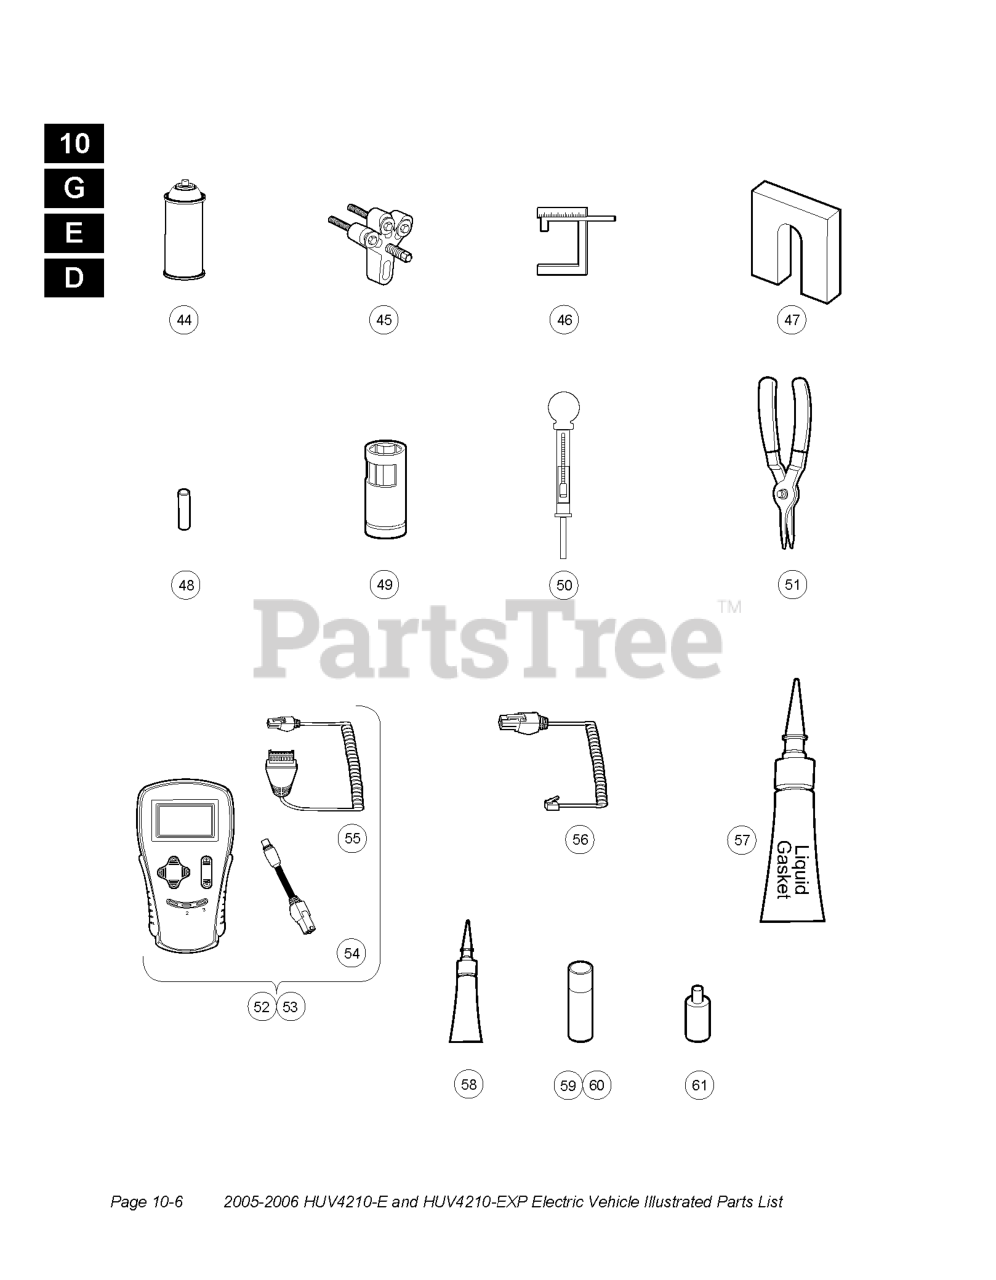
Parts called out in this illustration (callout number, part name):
44	LUBRICANT 11OZ CAN SPRAY
49	ADJUSTER, HYDRAULIC BRAKE
50	HYDROMETER
51	INERNAL RETAINING RING PLIERS
52	KIT, IQDM, USER, SERIES II
53	KIT, IQDM, OEM, SERIES II
54	ADAPTER, 1307 CABLE
55	CABLE, IQDM, SERIES II
56	CABLE, IQDM
58	LUBRICANT, MOLY-TEFLON,4 OZ TU
59	TOUCH UP PAINT, DARK GRAY
59	TOUCH UP PAINT, CLASSIC BLUE
59	TOUCH UP PAINT, GRAY
59	TOUCH UP PAINT, WHITE
59	TOUCH UP PAINT, BURGUNDY
59	TOUCH UP PAINT, RED
59	TOUCH UP PAINT, DARK GREEN
59	TOUCH UP PAINT BEIGE
59	TOUCH UP PAINT, BLACK
59	TOUCH UP PAINT, ROYAL BLUE
60	PAINT, GRAY - SPRAY
61	PAINT PEN, UNDERBODY, BLACK
